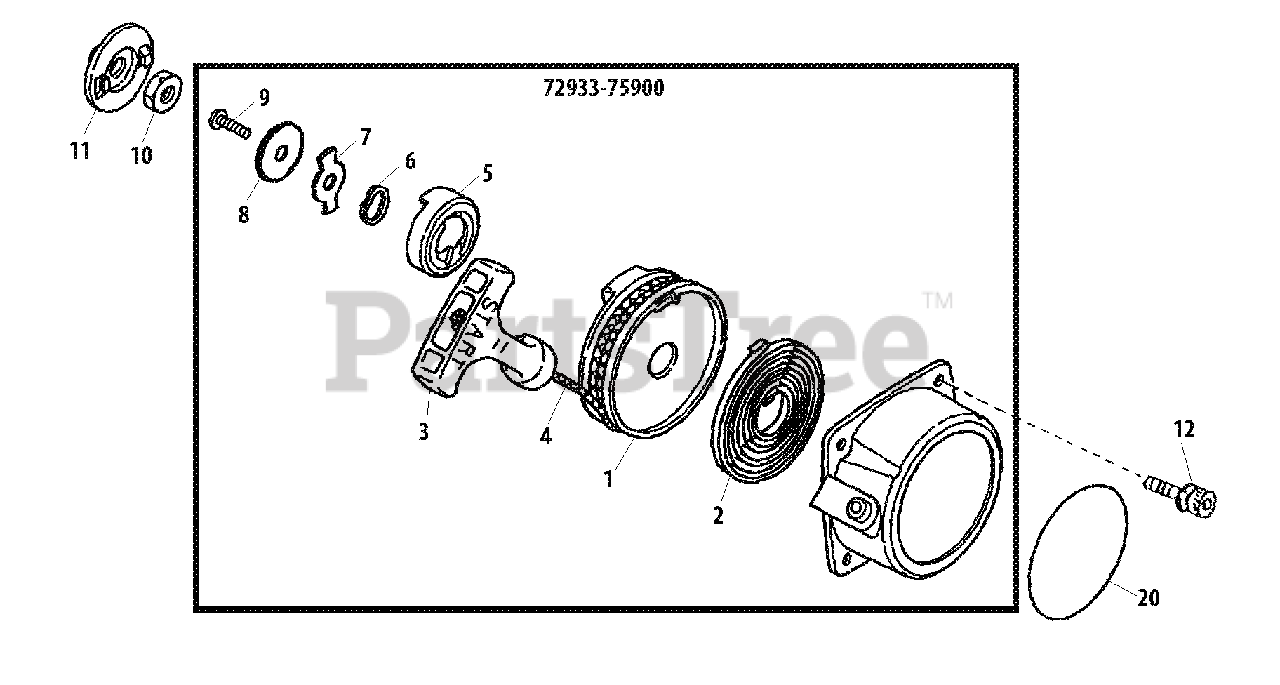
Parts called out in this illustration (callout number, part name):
1	REEL, ROPE
2	SPRING, RECOIL
3	GRIP, STARTER
4	ROPE, STARTER
5	RATCHET
6	WASHER, WAVE
7	RETAINER
8	WASHER 5 MM
9	SCREW 5 MM
10	NUT M8×1
11	PULLEY, STARTER
12	BOLT, ADHESIVE M4×12
20	LABEL, RECOIL STARTER
72933-75900	STARTER ASSY, RECOIL
